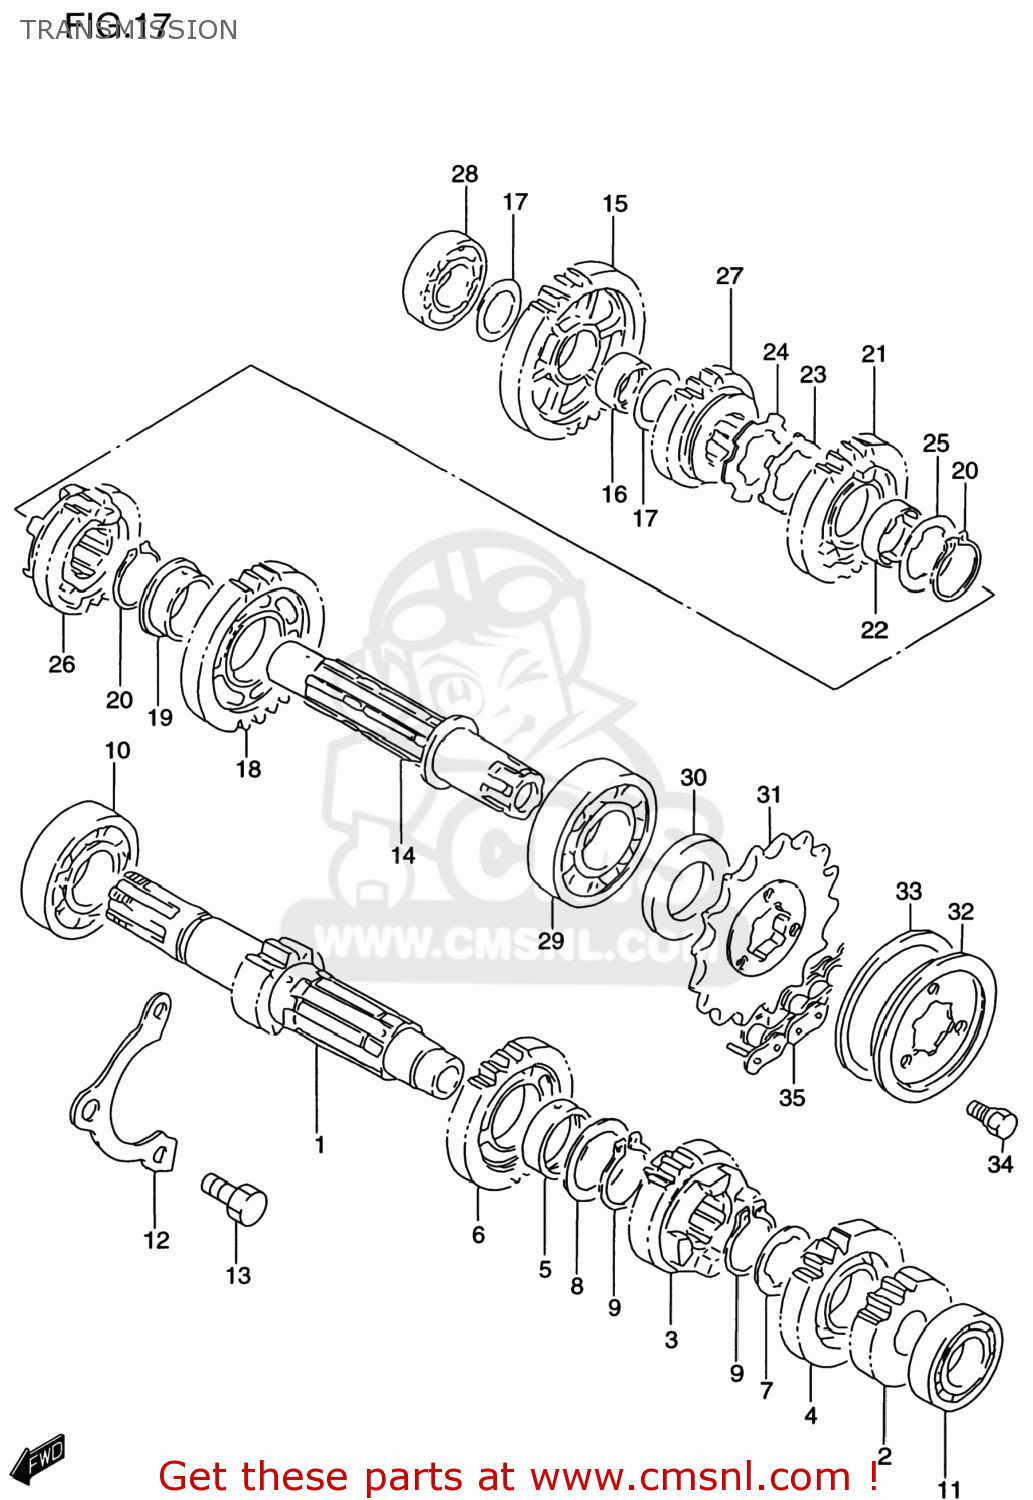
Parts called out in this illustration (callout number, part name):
1	SHAFT,COUNTER
2	GEAR,2ND DRIVE
3	GEAR,THIRD DRIVE
4	GEAR,4TH DRIVE
5	BUSHING 25X29X10
6	GEAR,5TH DRIVE
7	WASHER,LOCK
8	WASHER
9	RING,SNAP
10	BEARING(22X56X16)
11	BEARING
12	RETAINER,CNTR SHAFT BEARING
13	BOLT
14	SHAFT,DRIVE
15	GEAR,1ST DRIVEN
16	BUSH(20X24X13)
17	WASHER
18	GEAR,2ND DRIVEN
19	BUSH
20	RING,SNAP
21	GEAR,3RD DRIVEN
22	BUSHING
23	WASHER
24	WASHER,LOCK
25	WASHER,LOCK
26	GEAR,4TH DRIVEN
27	GEAR,5TH DRIVEN
28	BEARING(20X42X12)
29	BALL BEARING 25X62X17
30	SEAL,OIL(25X44X7)
31	SPROCKET,ENGINE(15T)
32	PLATE,ENGINE SPROCKET
33	DAMPER,ENGINE SPROCKET
34	BOLT(6X13)
35	CHAIN,DRIVE(DID525V9,110L)
